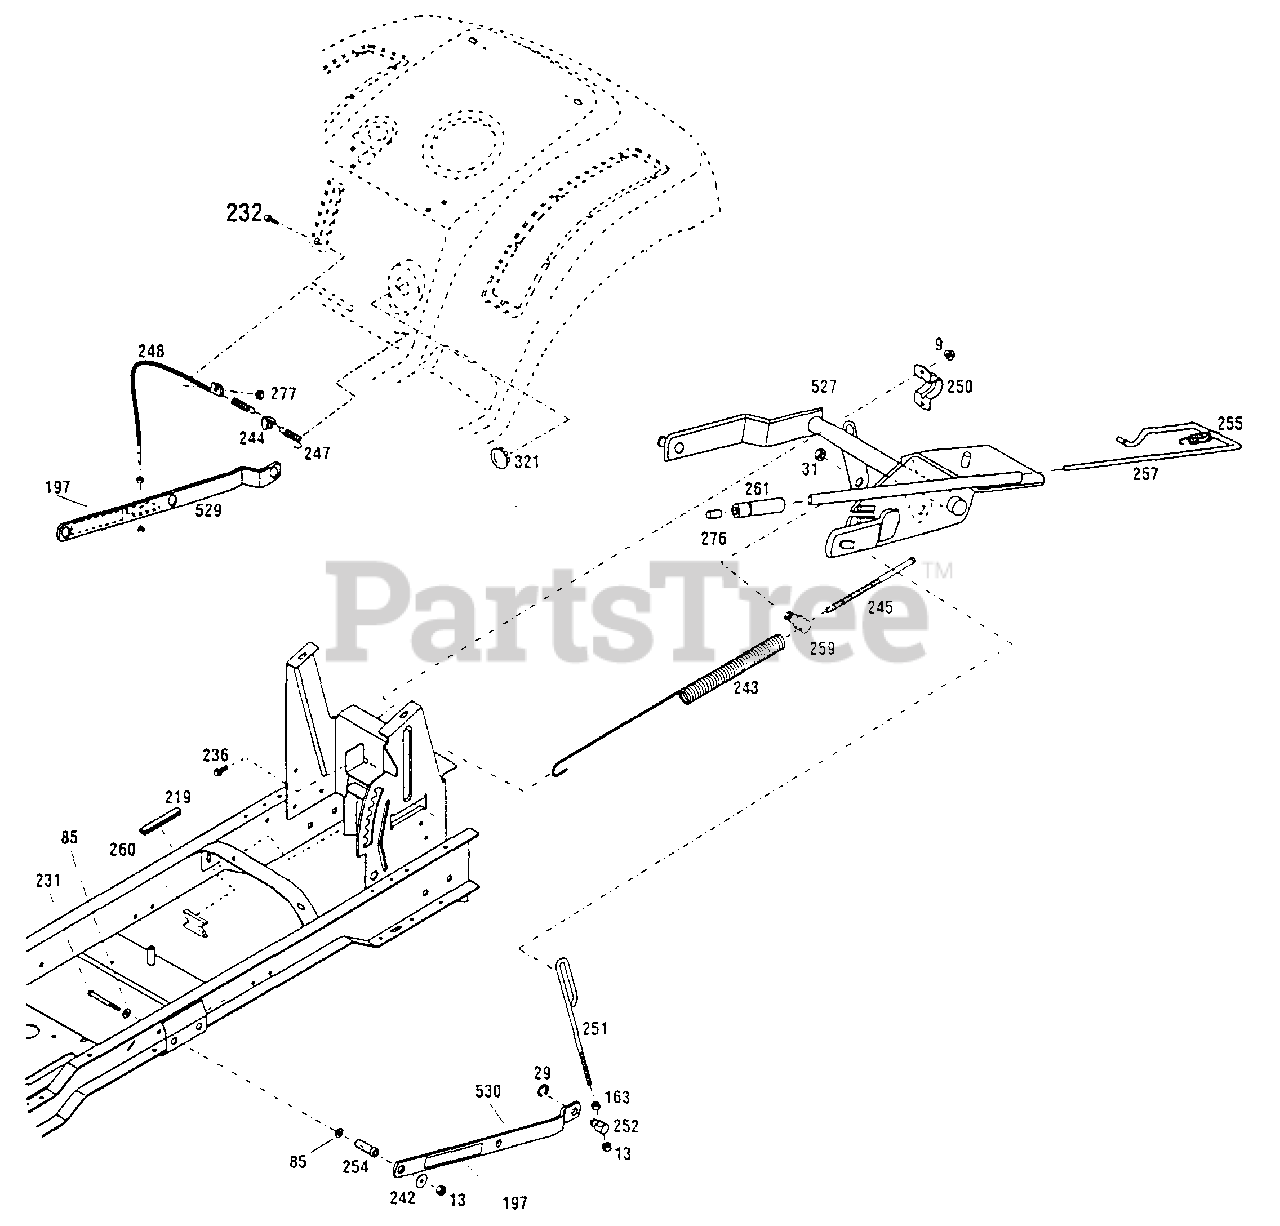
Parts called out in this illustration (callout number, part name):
9	Flange Nut, 5/16-18
13	Top Locknut, 3/8-16
29	E Retaining Ring, 5/8
31	Top Locknut, 5/8-11
85	Flat Washer, 3/8
163	Hex Nut, 3/8-16
197	Warning Decal
231	Hex Head Screw, 3/8-16 x 3
232	Screw, 10-24 x 5/16
236	Flange Screw, 5/16-18 x 3/4
242	Flat Washer, 3/8 x 1-1/2
243	Lift Assist Spring
244	Height Indicator
245	Hex Head Screw, 3/8-16 x 5
247	Extension Spring
248	Cable Assembly
250	Lift Clamp
251	Lift Rod
252	Rear Lift Swivel
254	Spacer
255	Extension Spring
259	Pivot Block
260	Spring Anchor
261	Lift Grip
276	Lift Button
321	Dome Cap
527	Lift Assembly
529	Right Lift Link Assy.
530	Left Lift Link Assy.
